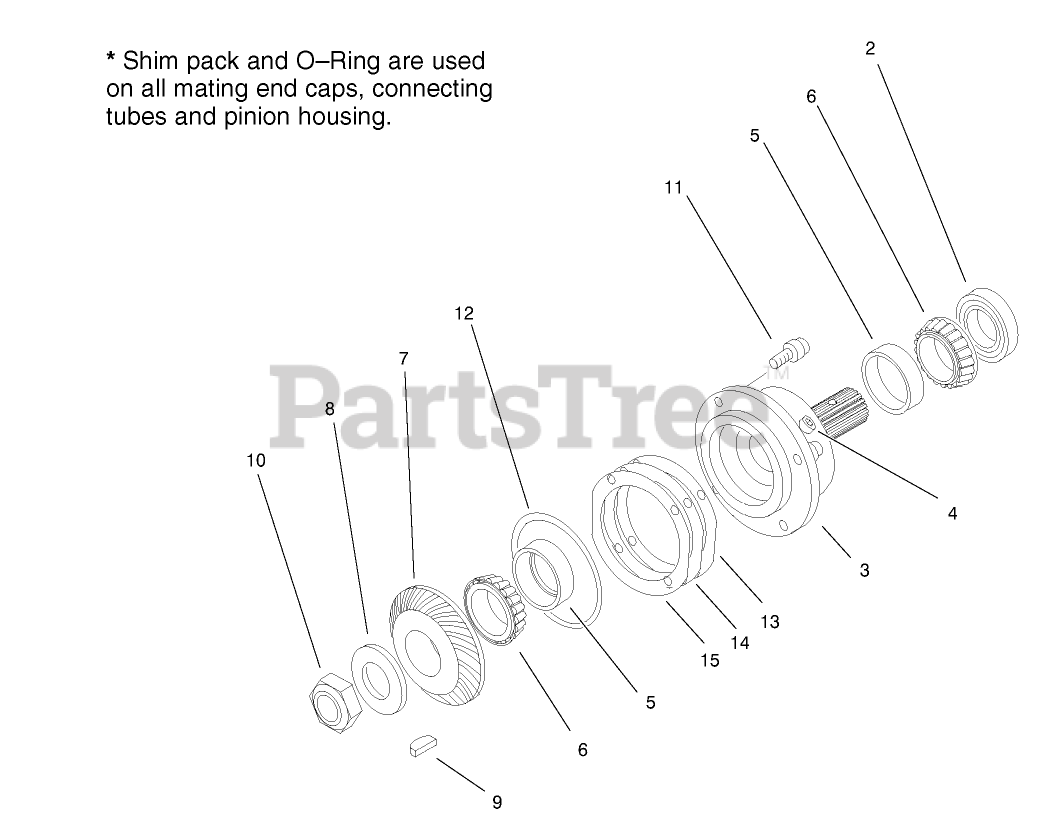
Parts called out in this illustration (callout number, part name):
3	HOUSING - PINION
5	Bearing-Cup
6	Bearing-Cone
7	GEAR - 27 TOOTH
8	WASHER
9	KEY-WOODRUFF
10	NUT-JAM
12	O-RING
13	SHIM-BROWN, .010IN
14	SHIM-BLUE, .005IN
15	SHIM-GREEN, .003IN
